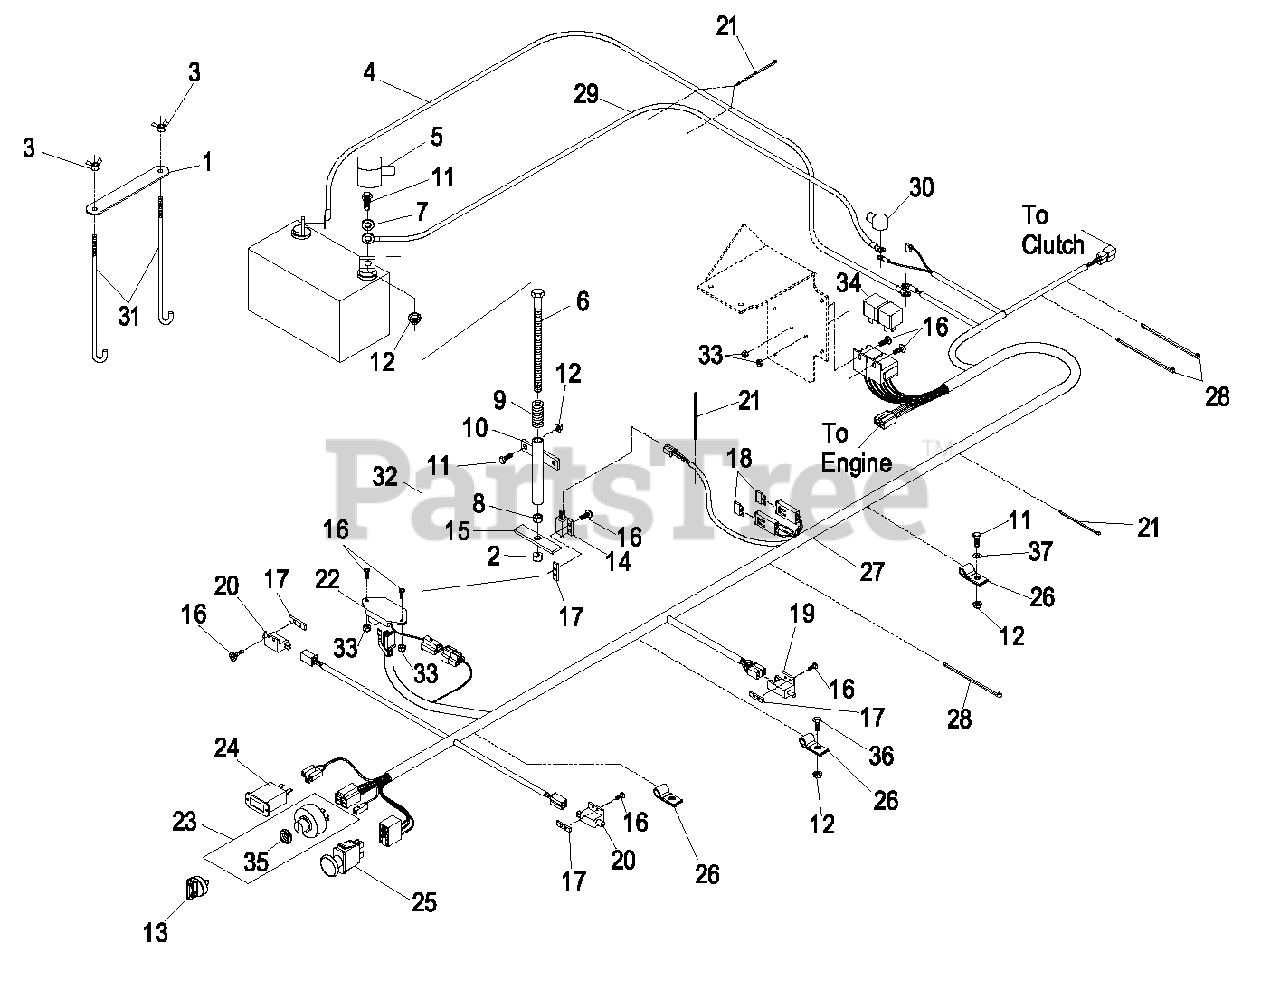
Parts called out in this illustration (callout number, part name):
1	STRAP-HOLDDOWN, BATTERY
2	NUT-LOCK, NI
3	WINGNUT
4	WIRE-GROUND
6	SCREW-HH
7	WASHER-FLAT
8	NUT-HEX
9	SPRING-SWITCH, SEAT
10	MOUNT-SPRING, SEAT
11	SCREW-HH
13	KEY-IGNITION
13	KEYS-IGNITION (SPARE PAIR
14	SWITCH-CLOSED, NORMALLY
15	PLATE-SWITCH, SEAT
16	SCREW-PPH
17	PLATE-TAPPED
18	FUSE-BLADE TYPE, 20 AMP
20	SWITCH-OPEN, NORMALLY
21	TIE-CABLE
22	MODULE-DELAY, SEAT
23	ASM,SWITCH W/NUT
24	METER-HOUR
25	SWITCH-PTO
26	CLIP-LOOM
27	HARNESS, WIRE LAZER AS
28	TIE-PLASTIC
30	INSULATOR-SOLENOID
31	BOLT-HOLDDOWN
32	ASM,SEAT SWITCH ACTUATOR
33	NUT-LOCK, NI
35	NUT-SWITCH, IGNITION
36	SCREW-HH
37	WASHER-FLAT
